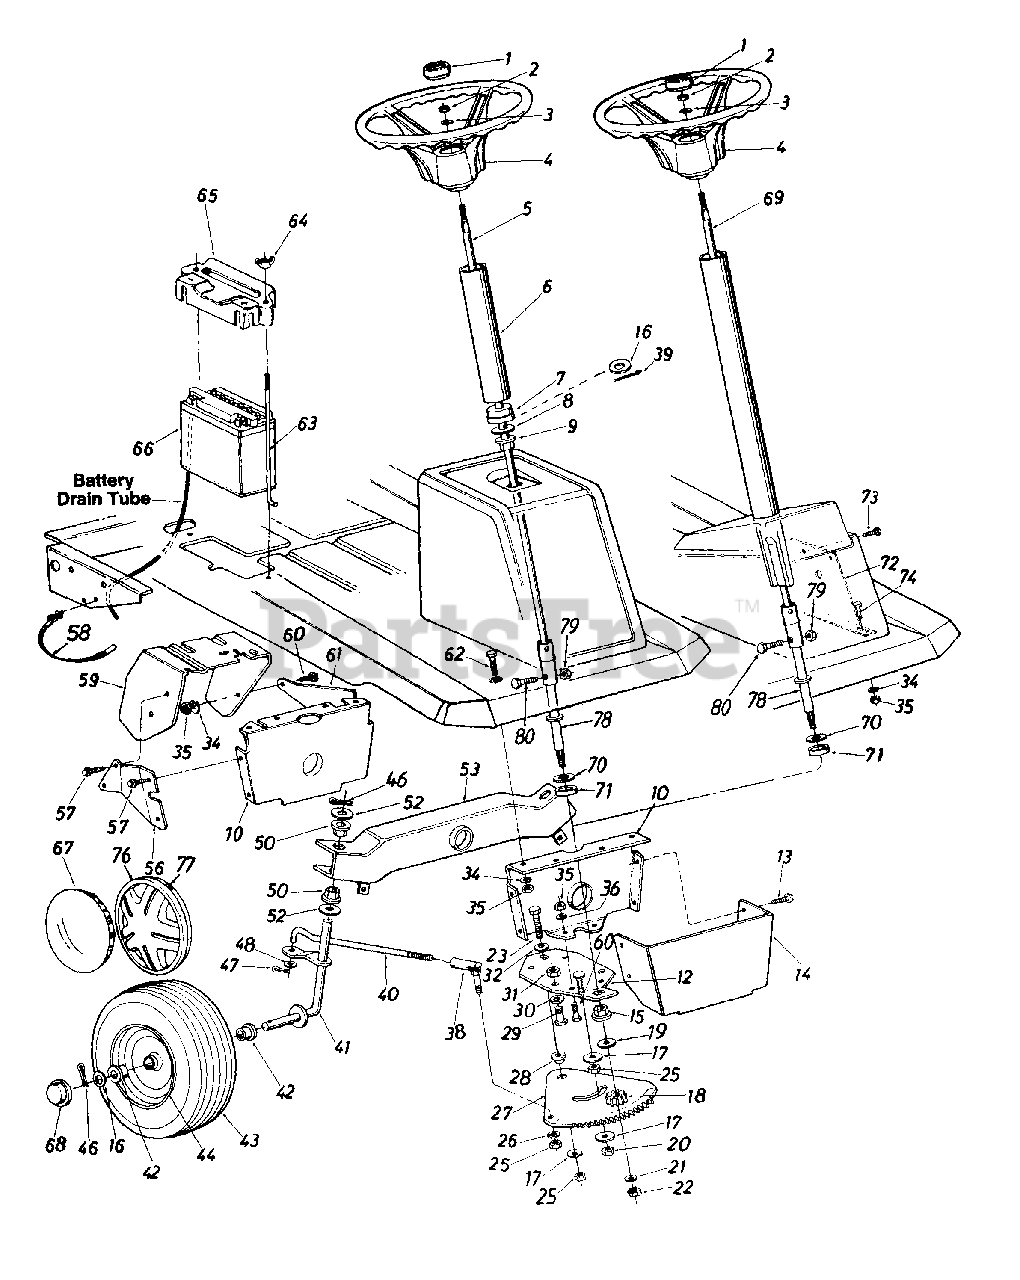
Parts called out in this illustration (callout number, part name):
1	Steering Wheel Cap
2	Hex L-Nut 5/16-24 Thd.
3	Bell-Wash. .345" I.D. x .88" O.D.
4	Steering Wheel Ass'y. (3 Spoke)
5	Steering Shaft Ass'y.
8	Fl-Wash. .635" I.D. x 1.24" O.D.
9	Hex Flange Bearing
13	Hex Wash. Hd. AB-Tap Scr. 1/4 x .62" Lg.
16	Fl-Wash. .640" I.D. x 1.5" O.D.
17	Fl-Washer 3/8" I.D. x 1.37" O.D.
18	Steering Pinion Gear
19	Fl-Wash. .510" I.D. x 1" O.D.
20	Hex L-Nut 3/8-24
21	Fl-Wash. .34" I.D. x .68" O.D.
22	Hex Nut 5/16-24 Thd.
23	Hex Bolt 3/8-24 x 1.5" Lg. (Grade 5)
25	Hex Nut 3/8-24 Thd.
26	L-Wash. 3/8" I.D.
27	Steering Gear Segment
28	Shoulder Spacer .622" Dia. x .218
29	Hex Bolt (Nylon) 1/2-13 x .75"
30	Fl-Wash. .530" I.D. x.930"
31	Hex Nut 1/2-13 Thd.
32	Bell-Wash. .385" I.D. x .88"
34	L-Wash. 5/16" I.D.
35	Hex Nut 5/16-18 Thd.
36	Spr. Wash. .32" I.D. x.62" O.D.
38	Ball Joint Ass'y. 3/8-24 Thd.
39	Cotter Pin 1/8" Dia. x 1.00" Lg.
40	Steering Tie Rod
41	Front Axle Ass'y.- R.H.
42	Flange Bearing
47	Cotter Pin 1/8" Dia. x 1.00"
48	Fl-Wash. .385" I.D. x .87"
50	Hex Flange Bearing
52	Fl-Wash. .635" I.D. x 1.12"
53	Pivot Bar Ass'y.
58	Cable Tie
59	Clutch-Brake Pedal Ass'y.
60	Hex Bolt 5/16-18 x .75" Lg.
63	Battery Hold Down Rod
64	Wing Nut Solid 1/4-20 Thd.
65	Battery Hold Down Cover
66	12V Battery
67	Chrome Hub Cap
68	Plastic Hub Cap
69	Steering Shaft Ass'y.
70	Fl-Wash..635" I.D. x 1.24" O.D.
71	Spacer (Plastic)
74	Hex Bolt 5/16-18 x 2.00" Lg.
76	Hub Cap - Beige
77	Spring Clip (Used w/Ref. 76)
78	Steering End Adapter
79	Hex Nylon L-Nut 1/4-20 Thd.
80	Hex Bolt 1/4-20 x 1.31" Lg.
